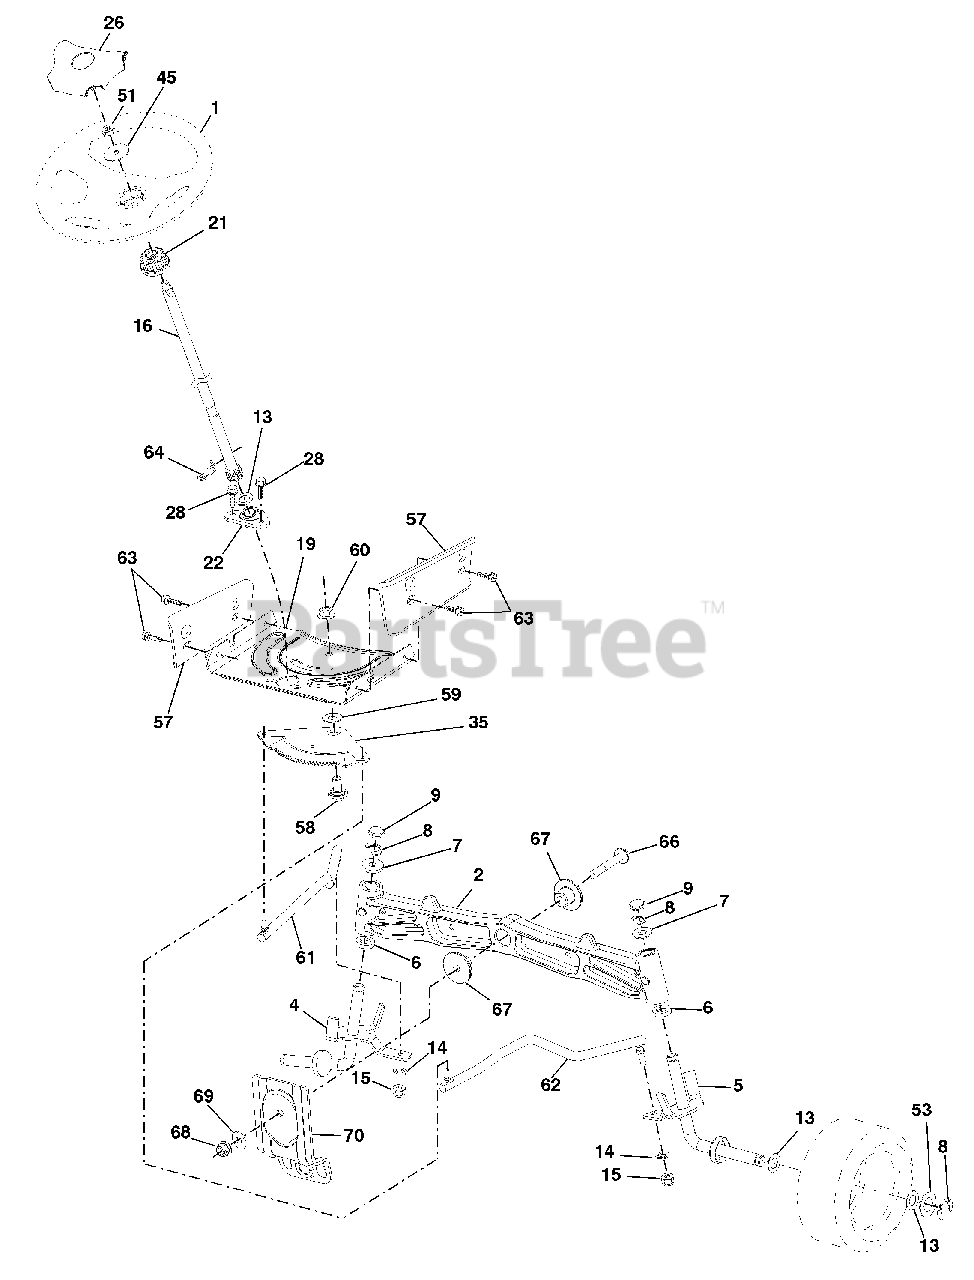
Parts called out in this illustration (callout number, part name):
1	Wheel, Steering
2	Axle Asm., Front
4	Spindle Asm., LH
5	Spindle Asm., RH
6	Bearing, Race Thrust Harden
7	Washer 25/32 x 1-5/8 x 16 Ga.
8	Ring, Klip #T5304-75
9	Cap, Spindle
13	Washer 25/32 x 1-1/4 x 16 Ga.
14	Washer, Lock Hvy Hlcl Spr 3/8
15	Nut, Crown Lock 3/8-24 unf
16	Shaft Steering
19	Plate Steering
21	Adapter, Wheel Steering
22	Bushing, Strg. Blk
26	Insert, Wheel Steering
28	Screw 3/8-16 x 3/4
35	Gear, Sector Plate
45	Washer 9/16 ID x 2-3/8 OD 12 Ga.
51	Nut Hex Jam Toplock 1/2-20 unf
53	Washer Hardened .793 x 1.637 x .060
57	Bracket Upstop
58	Bolt Shoulder Sector Pivot CFM
59	Washer Thrust Sector Steering
60	Nut Flange Lock 5/8-11
61	Draglink LH
62	Draglink, RH
63	Screw 5/16-18 x 3/4
64	Retainer Clip Spring Steering
66	Bolt Hex Fghd 7/16-14 x 3 Serr
67	Bushing PM Front Axle
68	Nut Lock Flange 7/16-14 Gr. 5
69	Washer 1.5 x .505 x .118
70	Bracket Deck Susp. Front
74	Bearing
